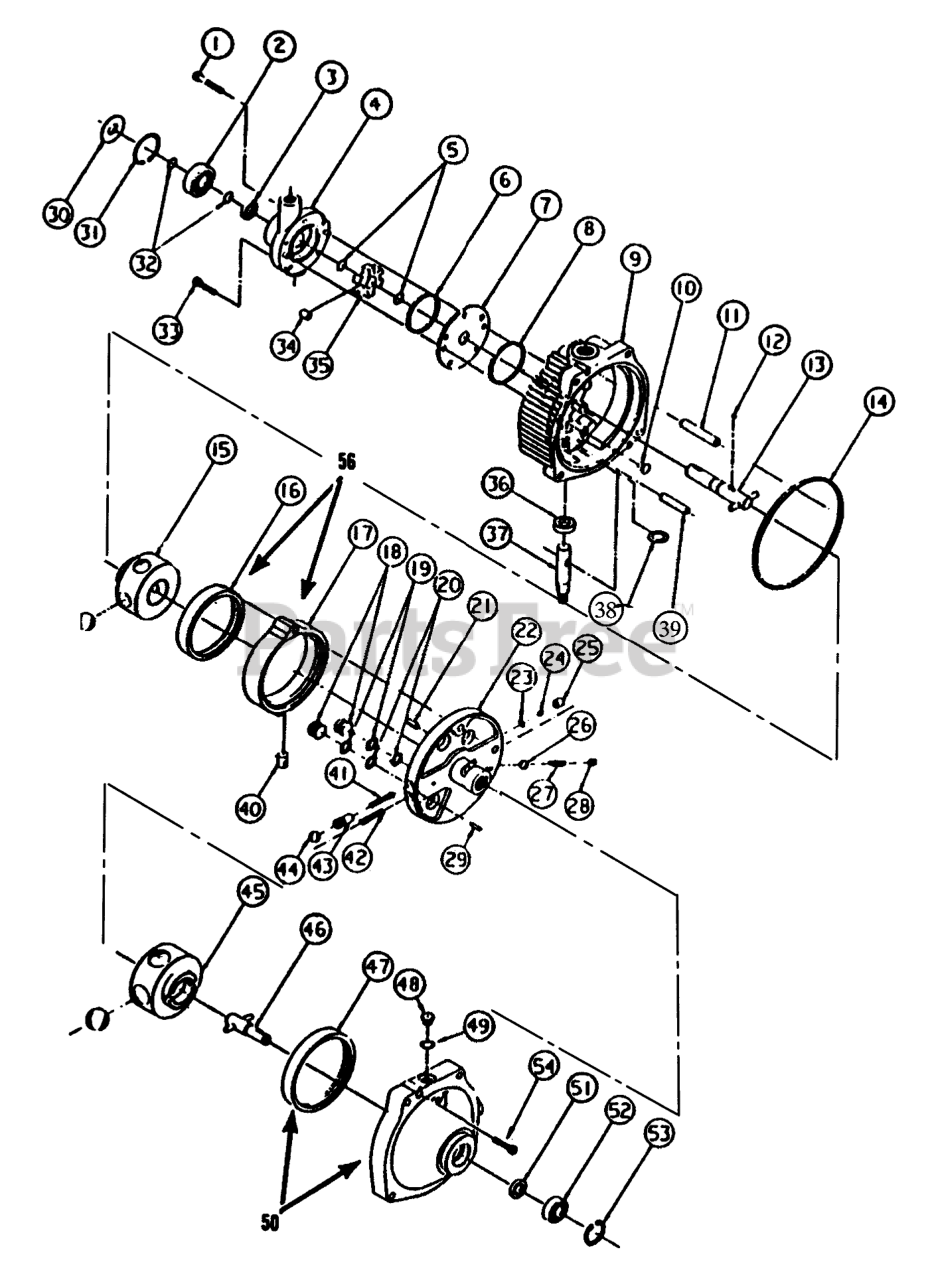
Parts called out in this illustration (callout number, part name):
1	Screw
2	Bearing-Input
3	Seal
4	Housing-Pump Assembly (Incl. Ref. #2)
5	Ring
6	Ring-Seal
7	Plate
8	Ring-Seal
9	Cover Assembly (Incl. Ref. #3, 6, 8, 10, 11, 19, 20, 36-39, & 51)
10	Button
11	Pin-Pivot
12	Pin
13	Shaft-Input
14	Ring-Seal
15	Rotor-Pump
16	PUMP-RACE
17	Ring-Cam
18	Piston
19	Ring-Back Up
20	"O" Ring
21	Pin-Coil
22	Pintle Assembly (Inc. Ref. #21, 23-29 & 41-44)
23	Ring-Retaining
24	Ball
25	Body-Check Valve
26	Ball
27	Spring-Relief Valve
28	Plug-Relief Valve
29	Pin
30	SHIELD-GRASS
31	RETAINING-RING
32	Ring
33	Screw
34	Roller
35	Carrier
36	Seal
37	Kit-Control
38	Washer
39	Dowel
40	Insert-Cam Ring
41	Spring-Acc. Valve
42	Spring-Acc. Valve
43	Body-Acc. Valve
44	Ball
45	Rotor-Motor
46	Shaft-Output
47	Race-Motor
48	Plug-"O"Ring (Incl. Ref. #49)
49	O-Ring
50	Body Assembly (Incl. Ref. #51, 53 & 54)
51	Seal ASM
52	Bearing-Output
53	Retaining Ring
54	Screw
55	Kit-Seal, Overhaul (Incl. Ref. #3, 6, 8, 14, 19, 20, 36, 49 & 51)
56	Ring-Cam
